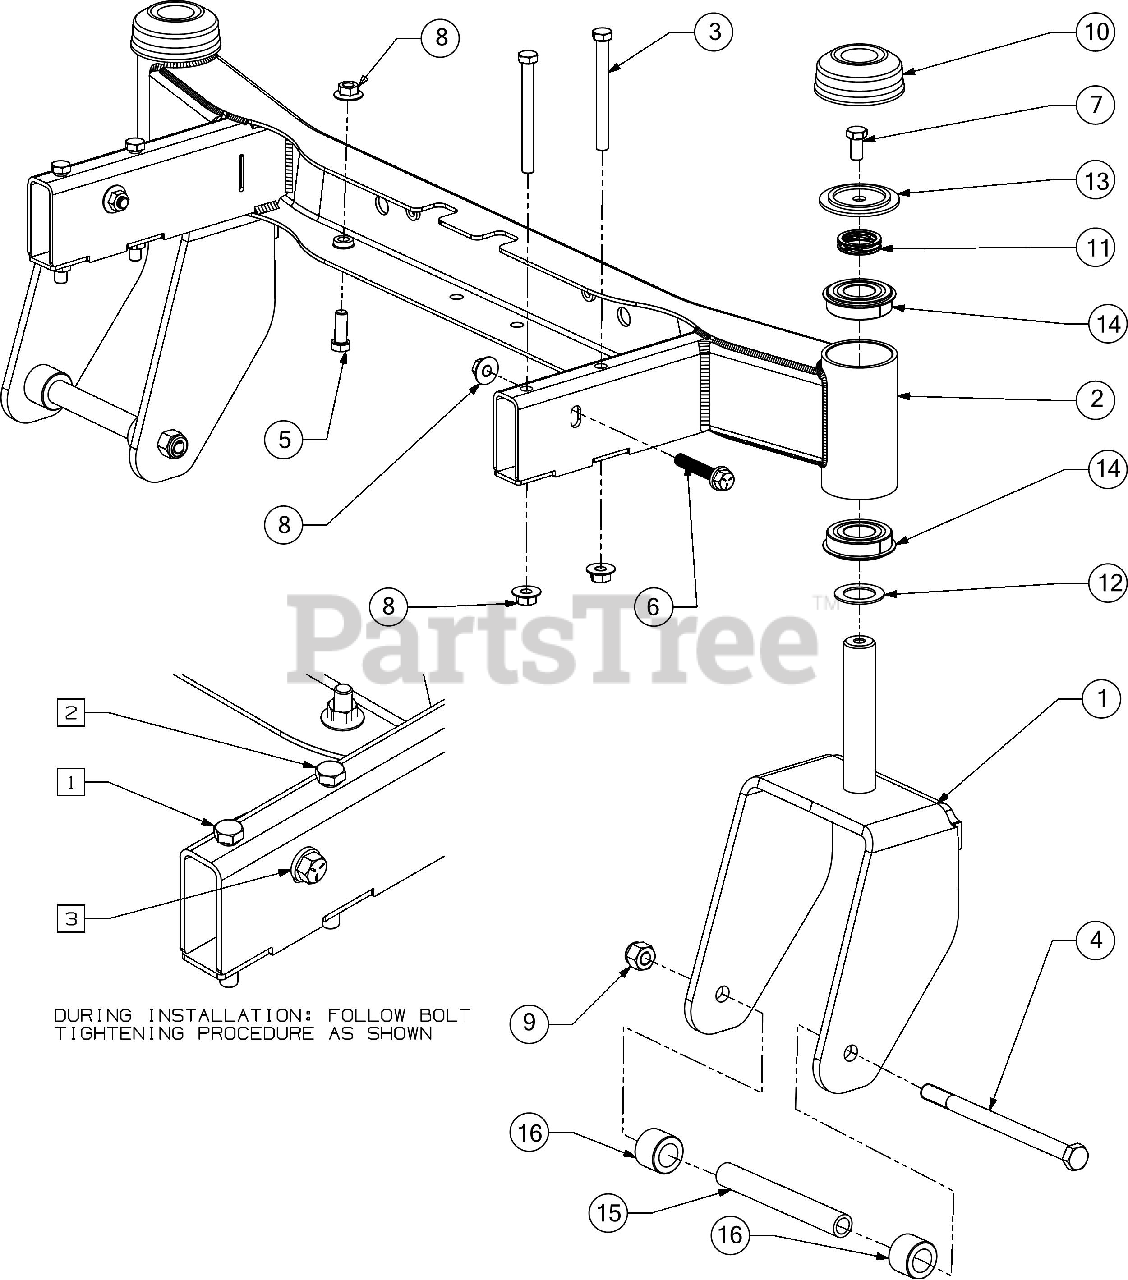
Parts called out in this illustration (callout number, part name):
1	CASTER WHEEL YOKE
2	FRONT AXLE ASSEMBLY 46/50/54
3	SCREW 3/8-16 x 3.75 GR5
4	BOLT 1/2-20 x 7.25 GR5
5	SCREW 3/8-16 x 1 GR5
6	SCREW 3/8-16 x 2.00 GR5
7	SCREW 3/8-16 x .75 GR 5
8	FLANGE LOCK NUT
9	HEX NUT CENTER
10	CASTER AXLE CAP
11	WAVE WASHER
12	WASHER 1.010X1.560X.060
13	SHOULDER SPACER
14	BALL BEARING
15	CASTER SPACER
16	HUB:76 x 1.23X.92 LG
